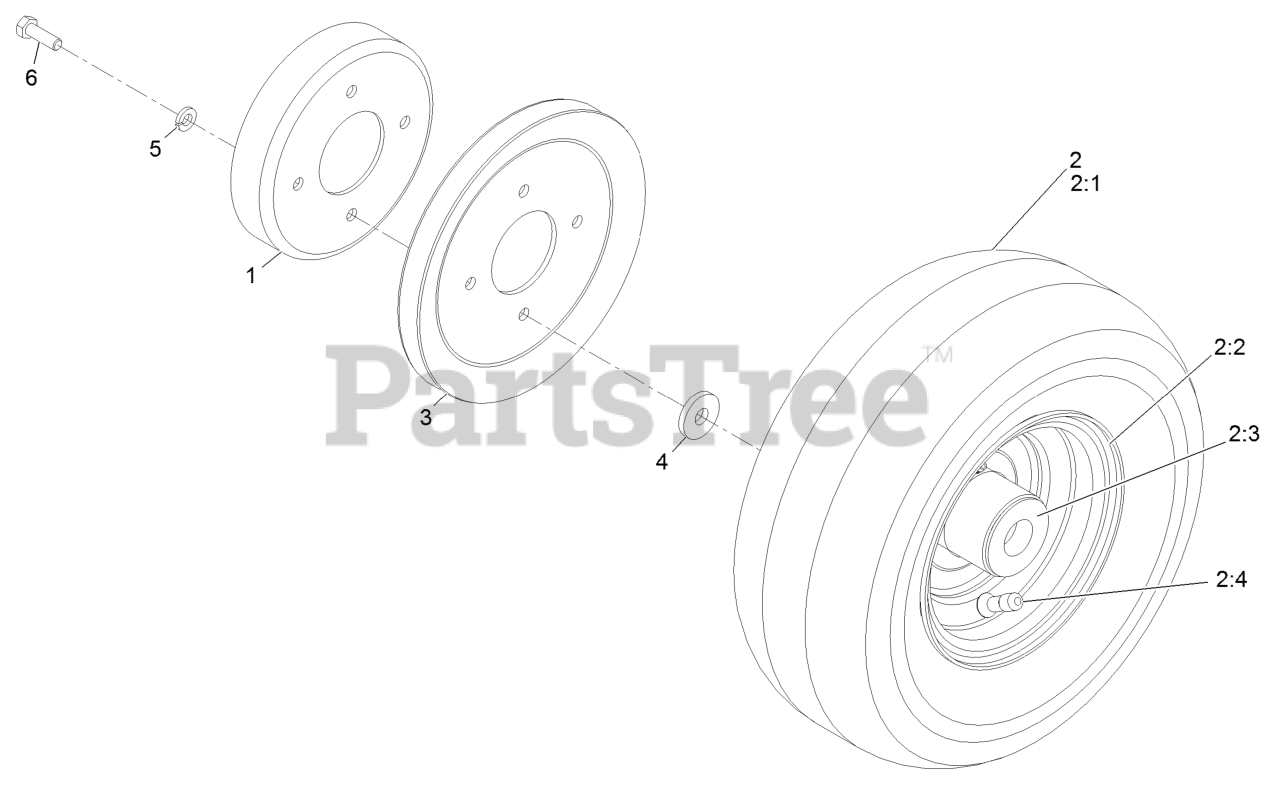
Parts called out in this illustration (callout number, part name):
1	DRUM-BRAKE
2	WHEEL AND TIRE ASM
2:2	WHEEL AND HUB ASM
2:3	Stem-Valve
2:4	FITTING-GREASE
3	SHEAVE-WHEEL, DRIVE
5	WASHER-LOCK
6	SCREW-HH
